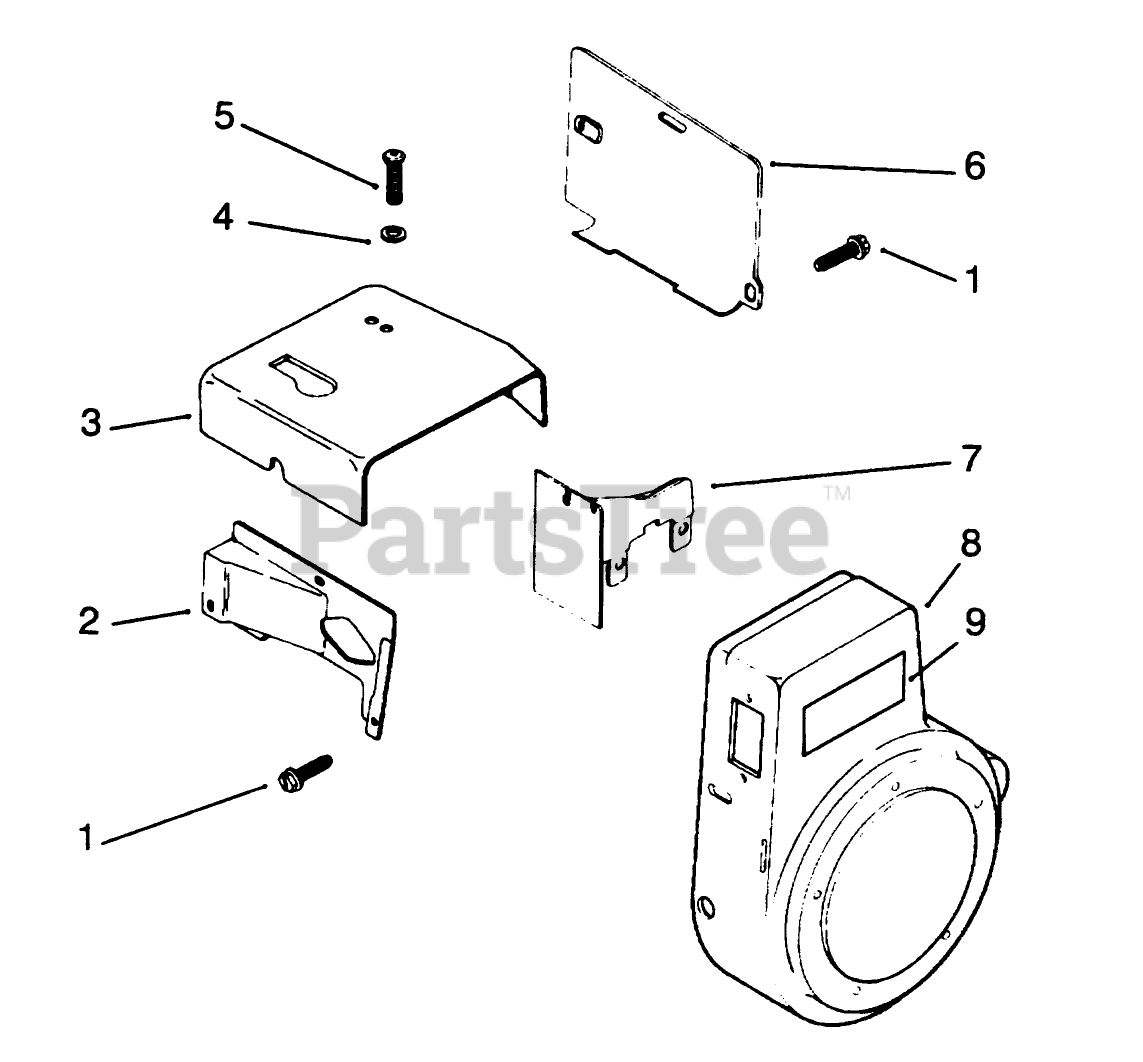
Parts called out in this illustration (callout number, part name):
1	KOHLER 52-086-11
2	KOHLER 47-063-06
3	KOHLER 45-063-08
4	KOHLER X-25-53
5	KOHLER 47-086-08
6	KOHLER 47-063-10
7	KOHLER 47-063-07
8	KOHLER 47-027-42
9	VNDR #47-113-36
